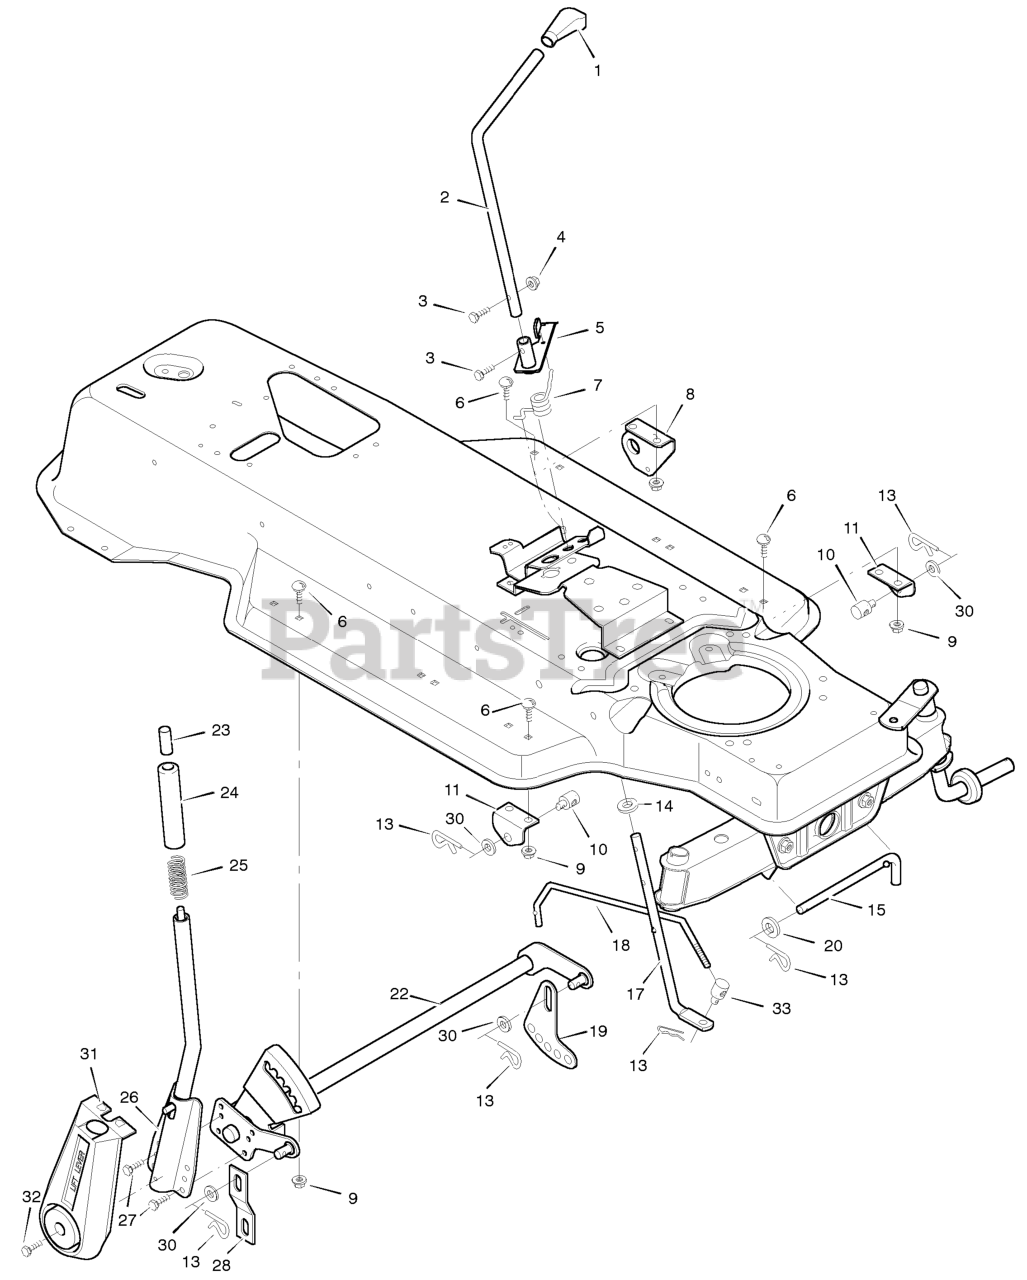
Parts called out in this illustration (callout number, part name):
1	Grip
2	Control, Blade Rotation
3	Screw, Hex
4	Locknut, Hex
5	Lever Assembly, Switch
6	Bolt, Carriage
7	Spring, Torsion
8	Bracket, Rear Hanger
9	Nut, Flange
10	Nut, Adjusting
11	Bracket, Adjuster Rod
13	Pin, Hair
14	Washer
15	Pin, Pull
17	Lever, Lower Blade Control
18	Rod, Blade Control
22	Lifter Assembly
23	Button, Push
25	Spring, Compression
26	Handle Assembly
31	Cover, Lift Lever
33	Nut, Adjusting
